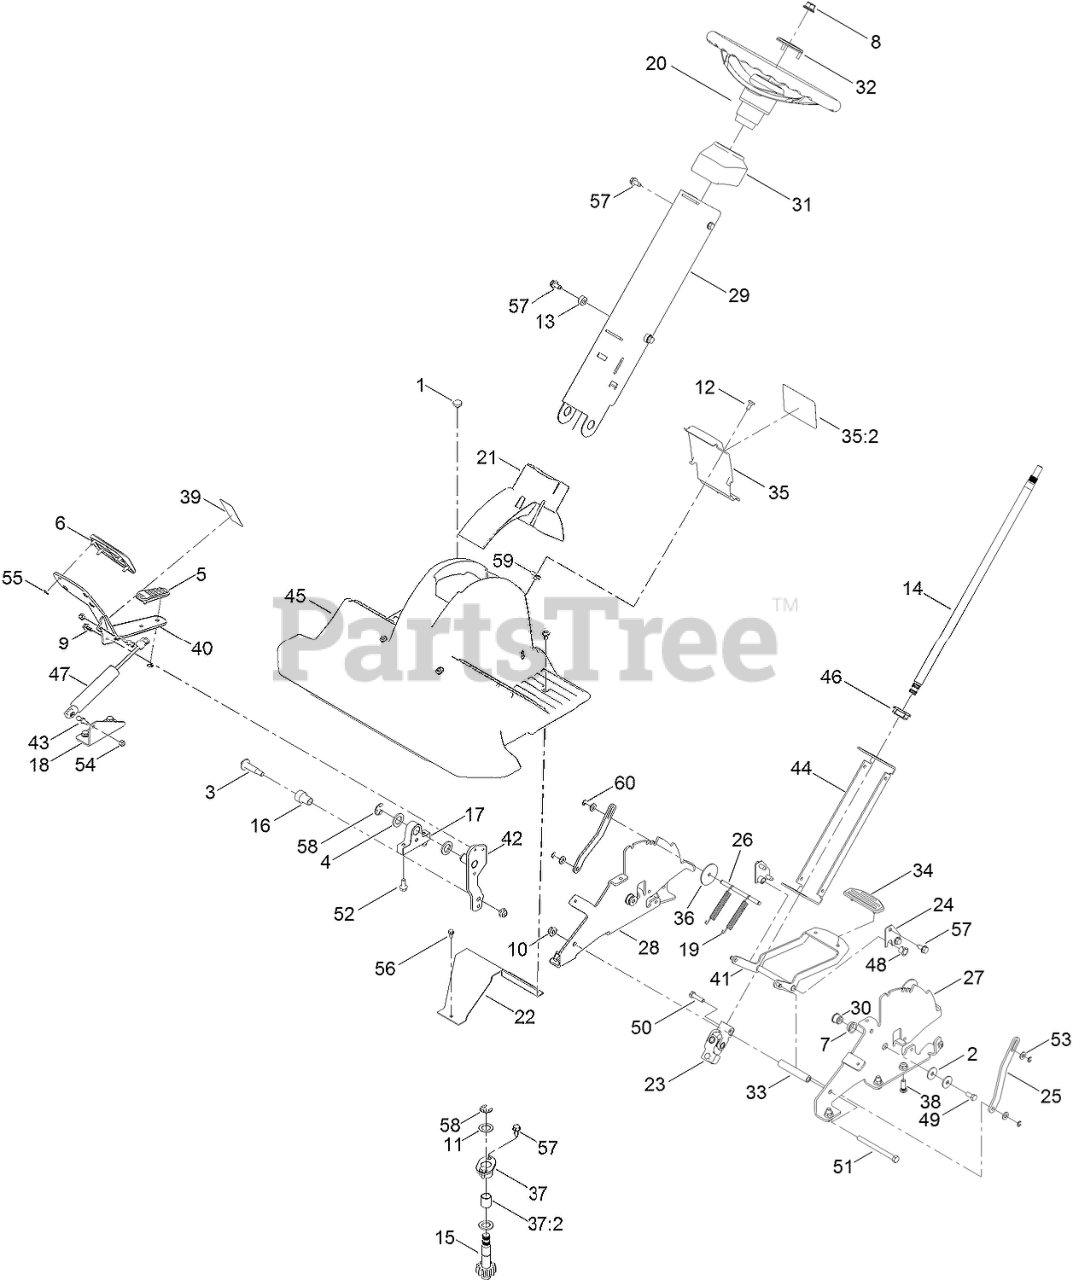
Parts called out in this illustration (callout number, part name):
1	BUMPER
2	WASHER-PIVOT
3	BOLT-SHOULDER
4	WASHER
5	PAD-HEEL, HYDRO PEDAL
6	PAD-TOE, HYDRO PEDAL
7	BUSHING-FLANGE
8	NUT-LOCK
9	SCREW-HHF
10	NUT-HF, NI
11	WASHER-THRUST
12	SCREW-SHOULDER
13	SPACER
14	SHAFT-STEERING, UPPER
15	LOWER STEERING SHAFT ASM
16	ROLLER
17	MOUNT-PEDAL PIVOT
18	BRACKET-DAMPER
19	SPRING-EXTENSION
20	WHEEL-STEERING
21	COVER-PIVOT, COLUMN
22	SUPPORT-FOOTREST
23	U-JOINT ASM
24	PLATE-RETAINER
25	PLATE-PLUNGER
26	ROD-PLUNGER
27	BRACKET-PIVOT, COLUMN (LH)
28	BRACKET-PIVOT, COLUMN (RH)
29	COLUMN-FRONT
30	SPACER-PIVOT, COLUMN
31	CAP-COLUMN
32	CAP-WHEEL, STEERING
33	SPACER
34	PAD-TILT PEDAL
35	REAR COVER AND DECAL ASM
35:2	DECAL-DANGER
36	WASHER-SHAFT, TILT
37	FLANGE BEARING ASM
37:2	BUSHING-STRAIGHT
38	STUD-PUSH-IN
39	DECAL-RELEASE, BREAK
40	PEDAL-TRACTION
41	RELEASE PEDAL ASM
42	PIVOT LEVER ASM
43	BALL STUD
44	COLUMN-BACK
45	SHROUD-STYLING, FRONT
46	BEARING-SPHERICAL
47	DAMPER-NON CAVITATING
48	BUSHING-NYLINER
49	SCREW-HH
50	SCREW-HH
51	SCREW-HH
52	SCREW-HHF
53	WASHER-PLAIN
54	NUT-LOCK, NI
55	NUT-PUSH
56	SCREW-HWH
57	SCREW-HWHTF
58	E-RING
60	E-RING
